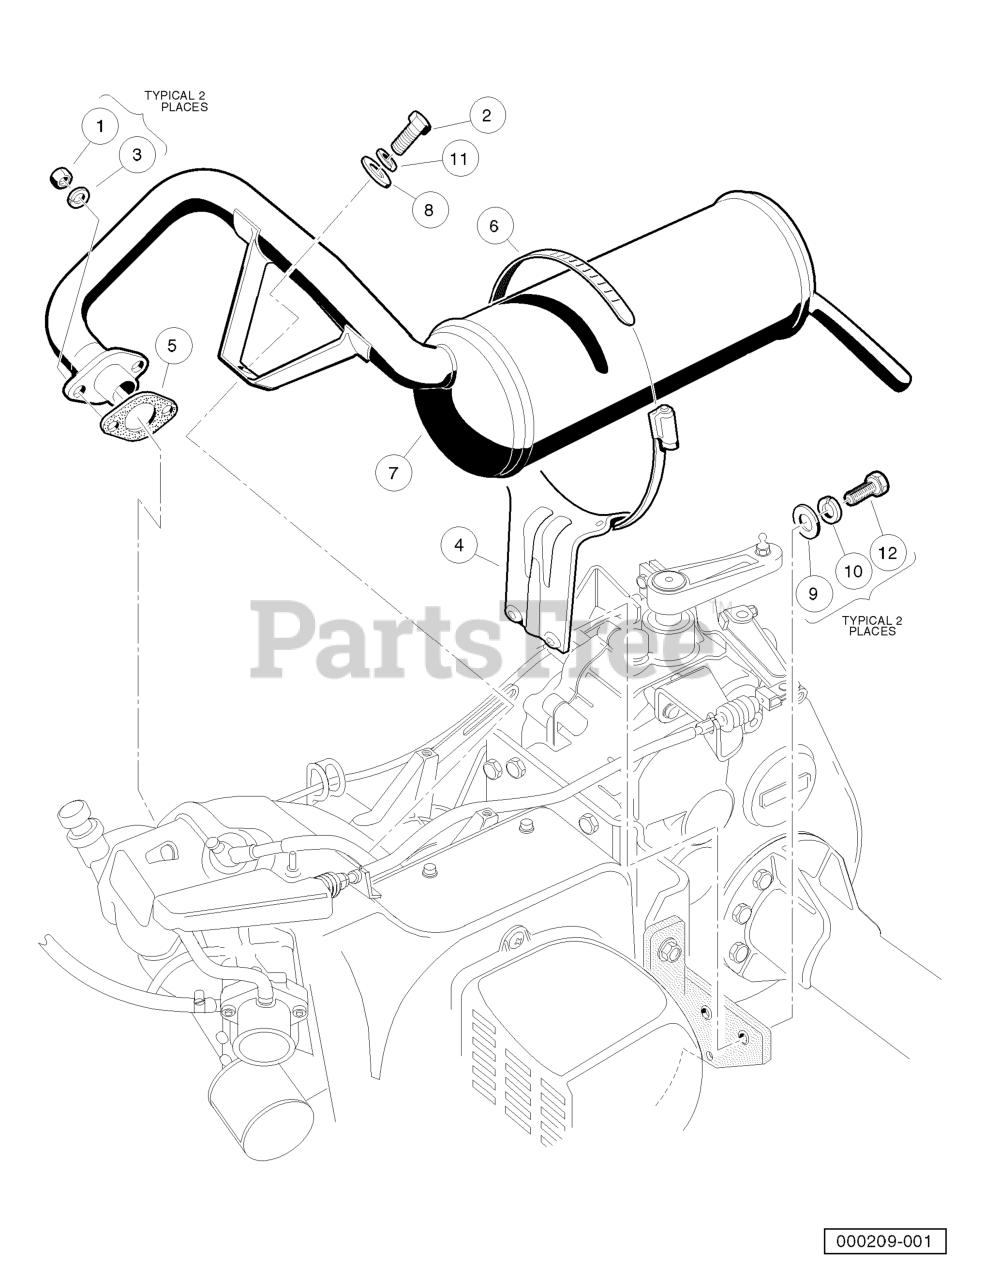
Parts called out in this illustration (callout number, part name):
1	NUT, M8-1.25 HEX
2	SCREW, M8-125 X 22 HEX GR.8.8
4	BRACKET, MUFFLER MOUNTING
5	GASKET, FE350 EXHAUST
6	CLAMP, 5" MUFFLER HOSE
7	EXHAUST SYSTEM, FE350
8	WASHER, 5/16 TYPE A FLAT
9	WASHER 1/4 FLAT
10	LOCKWASHER, 1/4 HELICAL SPLIT
11	LOCKWASHER, 5/16 SPLIT
12	SCREW, 1/4-20 X .75 HEX
